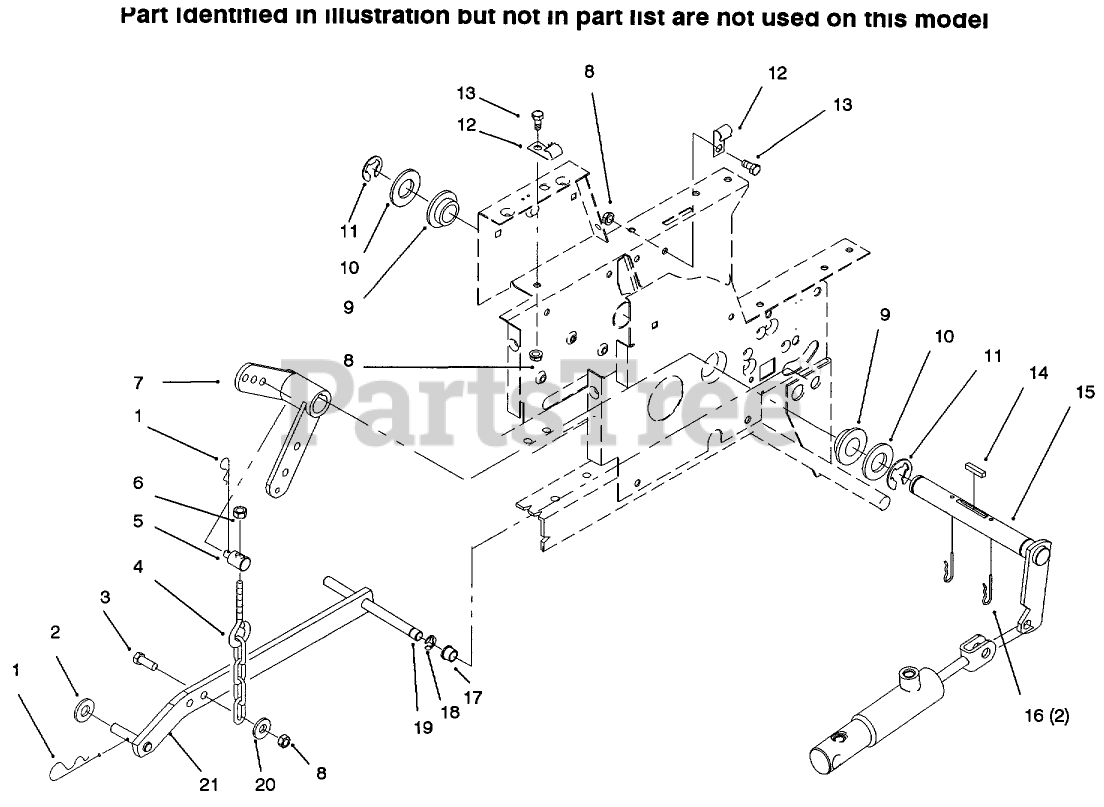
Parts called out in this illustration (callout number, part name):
1	PIN-HAIR
2	WASHER-FLAT
3	SCREW-HH
4	CHAIN-LIFT
5	TRUNNION
6	NUT-LOCK, NI
8	NUT-LOCK, NI
9	BEARING-FLANGE
10	WASHER-FLAT
11	RING-RETAINING
12	CLIP
13	SCREW-HH
14	KEY-SQUARE
16	PIN-HAIR
17	BUSHING
18	RING-RETAINING, EXTERNAL
19	PIN-PIVOT
20	WASHER-PLAIN
